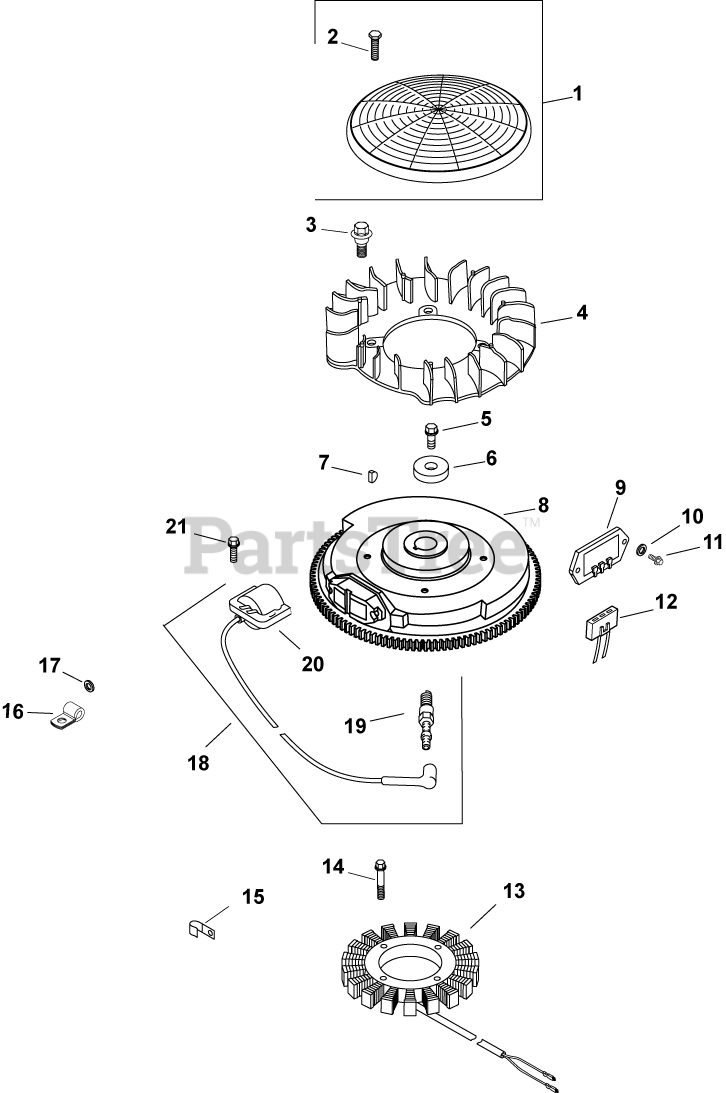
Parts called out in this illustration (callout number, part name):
1	KIT, GRASS SCREEN
2	SCREW, FLG SEMS M4X.7X25
3	BOLT, SHOULDER
5	SCREW, FLG M10X1.5X45 - (#25086361S)
6	WASHER, FLAT 13/32"
7	KEY, 3/16" X 5/8"
8	FLYWHEEL, PAINTED-USE 24 025 55-S
9	REG/RECT-15 AMP (KM)-USE 41 403 10-S
10	WASHER, FLAT 3/16"
11	SCREW, PHL HD #11-16X7/8"
12	CONNECTOR, BODY (KM)-USE 25 155 41-S
13	STATOR KIT - USE 237878-S
14	SCREW, M5X0.8X25 - (#25086402S)
15	CLIP, CABLE
16	CLIP, TUBE & WIRING (KM)
17	WASHER, FLAT 1/4" (O.D. 1/2")
18	IGNITION MODULE KIT-USE 25 707 01-S
19	SPARK PLUG - DISCONTINUED
20	MODULE, IGNITION - USE 24 707 06-S
21	SCREW, FLG THD FRM M5X.8X20-(#25086399S)
